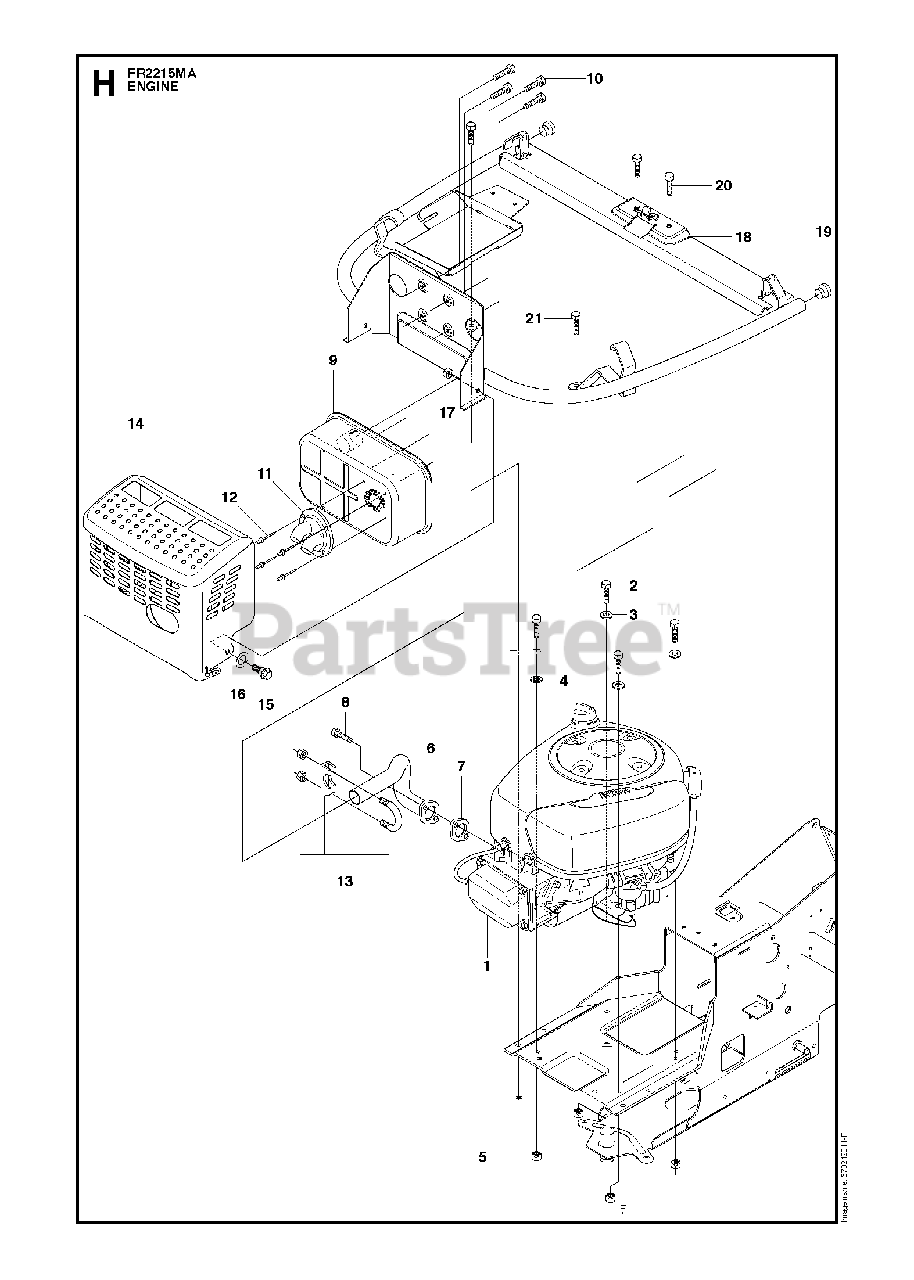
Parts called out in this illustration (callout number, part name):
3	WASHER BRB 8.4X17
5	LOCKNUT M8
9	MUFFLER
10	SCREW
13	CLAMP
16	SPRINGWASHER
17	LOCKNUT M8
